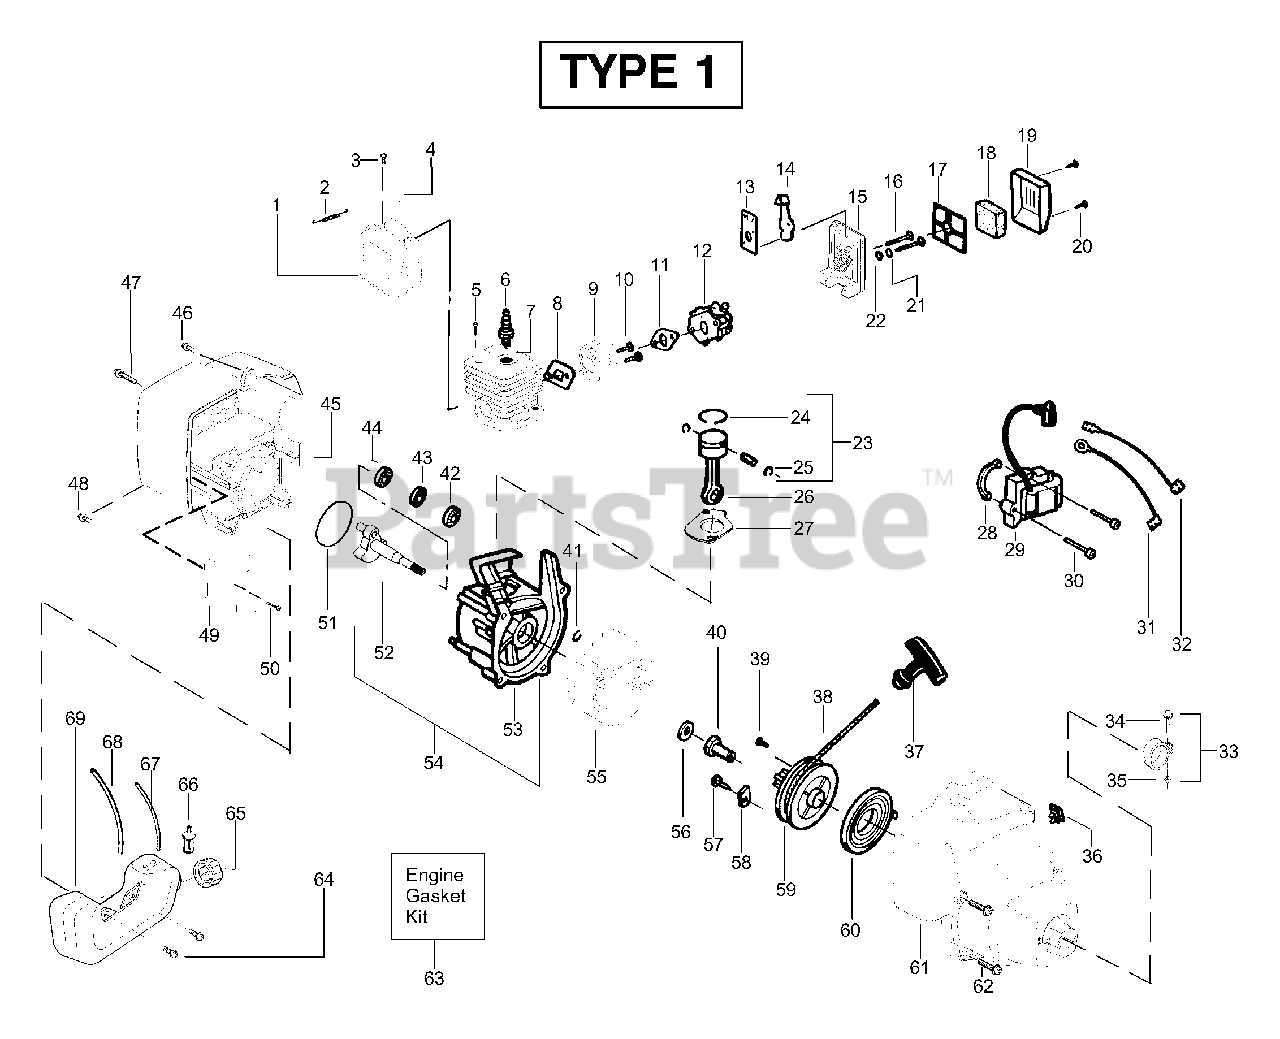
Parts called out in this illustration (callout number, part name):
1	Kit - Muffler
2	Spring-Muffler
3	Screw-Screen
4	Kit-Spark Arrestor
5	Screw-Cylinder
6	Spark Plug (RCJ 6Y)
7	Kit - Cylinder
8	Gasket-Cylind./Carb.
9	Adapter-Carb.
11	Gasket-Carb.
12	Kit-Carb.(C1U-W10B)
13	Choke Plate Mounting
14	Shutter-Choke
17	Plate - Filter Support
18	Foam-Air Filter
19	Cover-Air Filter
21	Spacer-Choke
23	Kit - Piston
24	Piston Ring
25	Retainer-Piston Pin
26	Assy-Connecting Rod
27	Gasket-Cylinder
28	Spacer-Module
29	Ignition Module
31	Assy-Ground Wire
32	Assy-Leadwire
33	Assy-Nose Cone Clamp
34	Screw-Nose Cone
35	Nut-Nose Cone
36	Kit-Switch
37	Handle-Starter
38	Kit - Rope
40	Coupling-Drive
41	Retain. Ring-C'shaft
42	Outer Bearing
43	Kit-C'case Seal
44	Inner Bearing
45	Shroud-Rear
47	Screw
49	Shield-Heat
50	Screw
51	O-Ring-C'case/Shrd
52	Assy-Crankshaft
53	Assy-Crankcase
54	Assy-C'case & C'shaft
55	Assy-Flywheel
56	Washer-Flat
58	Retainer-Can
59	Kit-Starter Pulley
60	Spring-Starter
61	Assy.-Fan Hsg
62	Screw
63	Kit-Engine Gasket
64	Retainer
65	Assy-Fuel Cap
66	Assy-Fuel Pickup
67	Kit-Fuel Line (Small)
68	Kit-Fuel Line (Large)
69	Assy-Fuel Tank
